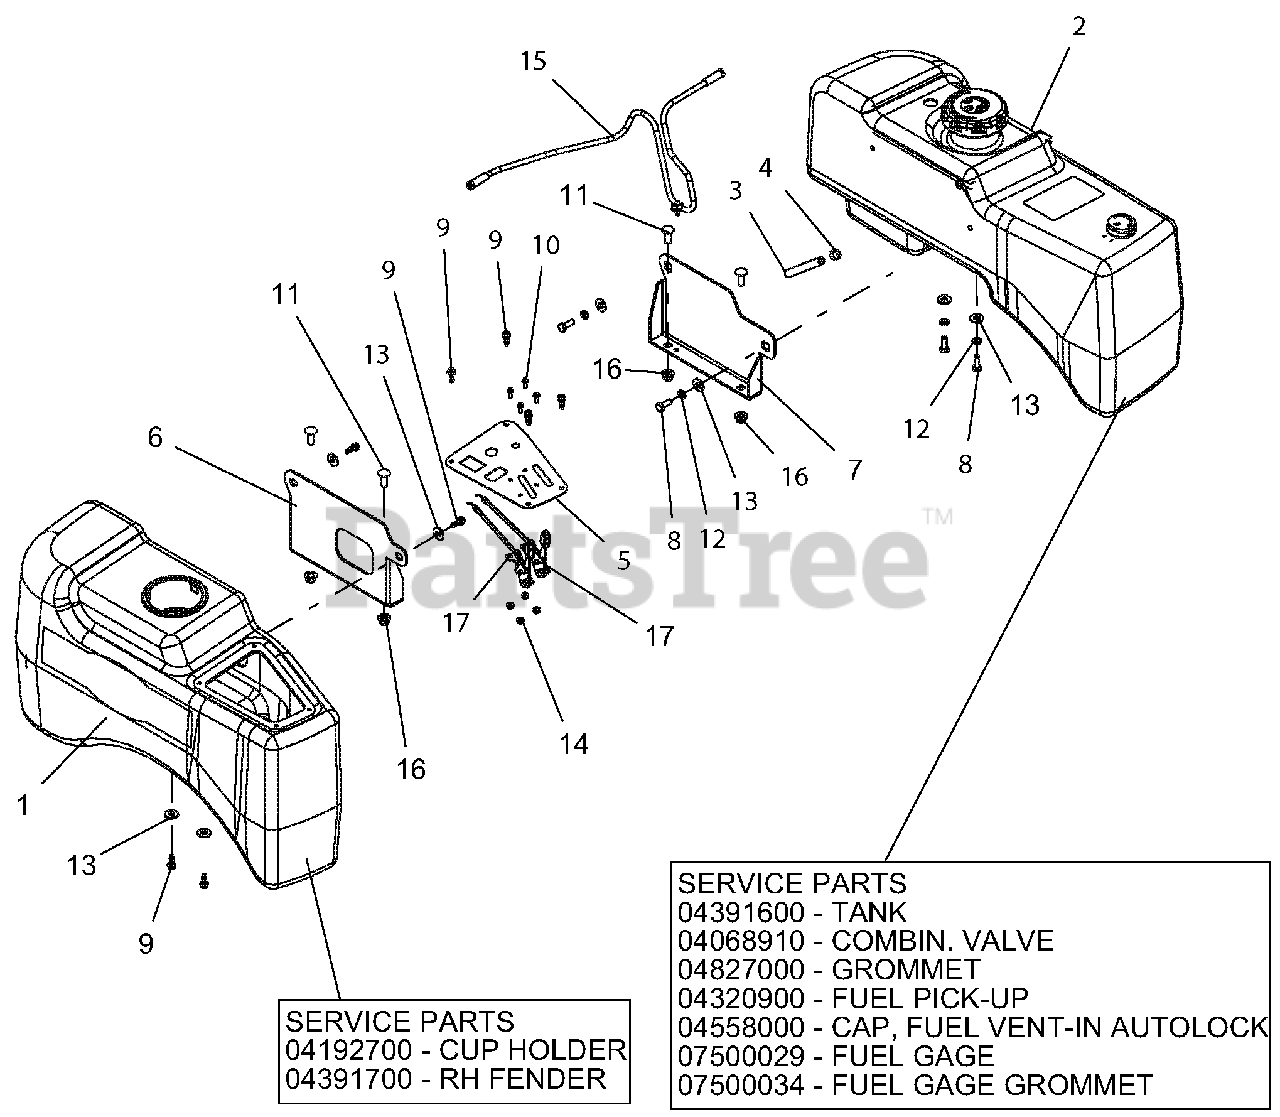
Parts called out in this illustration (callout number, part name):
1	ASM, FENDER W/CUPHOLDER
1	CUP HOLDER
1	RH FENDER
2	HD, FUEL TANK ASSEMBLY
2	TANK
2	COMBIN. VALVE
2	GROMMET
2	FUEL PICK-UP
2	CAP, FUEL VENT-IN AUTOLOCK
2	FUEL GAGE
2	FUEL GAGE GROMMET
3	.25 LOW-PERM GAS HOSE 18.50" LG - TANK TO ENGINE
4	CLAMP, FUEL LINE
5	PANEL, INSTRUMENT-BLACK
6	BRKT, RH HD FUEL TANK MTG-RED
7	BRKT, LH HD FUEL TANK MTG-RED
8	BLT-HEX .31-18X.875 GR5 YWZC
9	SCR-PLASTITE .25-10X.75 YWZC
10	@SCR-MCH 10-24X.50 HWH YWZC
11	BLT-RDHDSHSQNK.38-16X1.0 G5YZ
12	WSHR-LK .31X.078 REG YWZC
13	WSHR-FL-STL.38X.875X.083 YWZC
14	NUT-LK-NYL #10-24 YWZC
15	KAWASAKI, VENT LINE HD/PRO-TURN
16	NUT-LK-NYL-FLG .38-16 YWZC
17	CABLE, CONTROL
